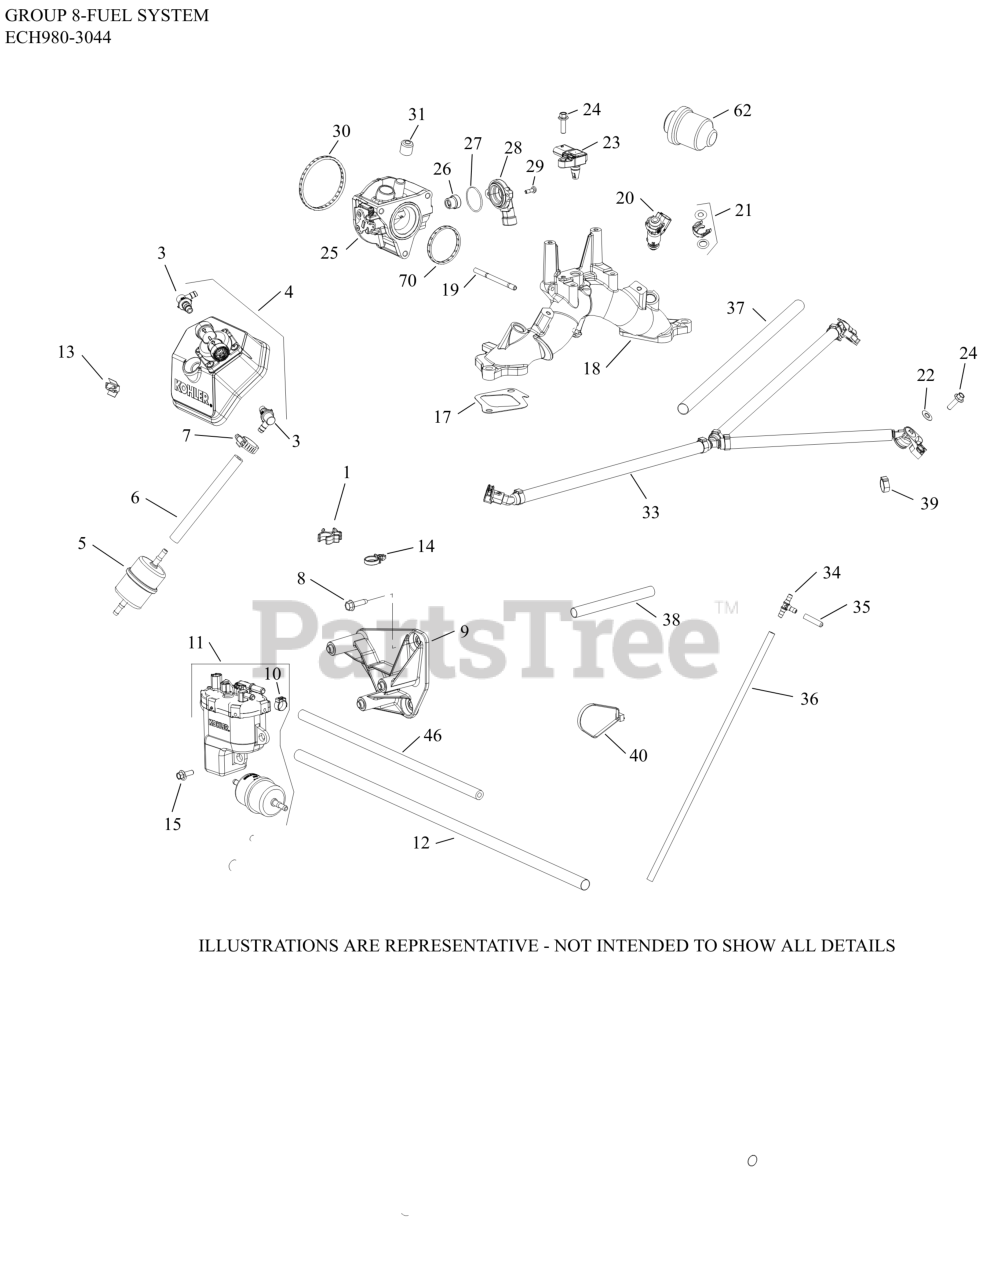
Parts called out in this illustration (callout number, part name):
1	RETAINER, HOSE
3	KIT, 90 DEG. FITTING
4	KIT, FUEL PUMP
5	FILTER, FUEL
6	HOSE,LW PERM.FUEL 24.00"-USE 25 111 81-S
7	CLAMP, HOSE (KM)-USE 25 237 31-S
8	SCREW, THREAD FORMING
9	BAFFLE, FUEL PUMP MODULE (HORZ)
10	CLAMP, OETIKER
11	FUEL PUMP
11	KIT,FP MODULE (ECH/ECV 440,630,940)
12	SLEEVE, ANTI ABRASION
13	CLIP, O2 SENSOR
14	CLIP, FUEL LINE
15	SCREW, FLG M6X1.0X16
17	GASKET, INTAKE MANIFOLD
18	MANIFOLD, INTAKE HORIZONTAL (EFI)
19	STUD,M6X1.0X84
20	INJECTOR, FUEL
21	KIT, FUEL INJECTOR O-RING
22	CLIP, RETAINER
23	SENSOR, T-MAP
24	SCREW, FLG M6x1.0x20
25	BODY, THROTTLE ASM (34)
26	MAGNET ASSEMBLY, TPS
27	O-RING, TPS SENSOR
28	SENSOR, THROTTLE POSITION
30	O-RING (HDAC SEAL-EFI)
30	O-RING, THROTTLE BODY
31	CAP, MASKING
33	RAIL ASSEMBLY, FUEL (HORZ)
34	TEE CONNECTOR
35	CAP, MASKING
36	HOSE, EVAPORATIVE
37	SLEEVE, ANTI ABRASION
38	SLEEVE, ANTI ABRASION -USE 25 431 12-S
39	CLAMP, HOSE
46	HOSE, FUEL (LOW-PREMEATION, 1/4" ID)
62	KIT, AIR FILTER SENSOR
